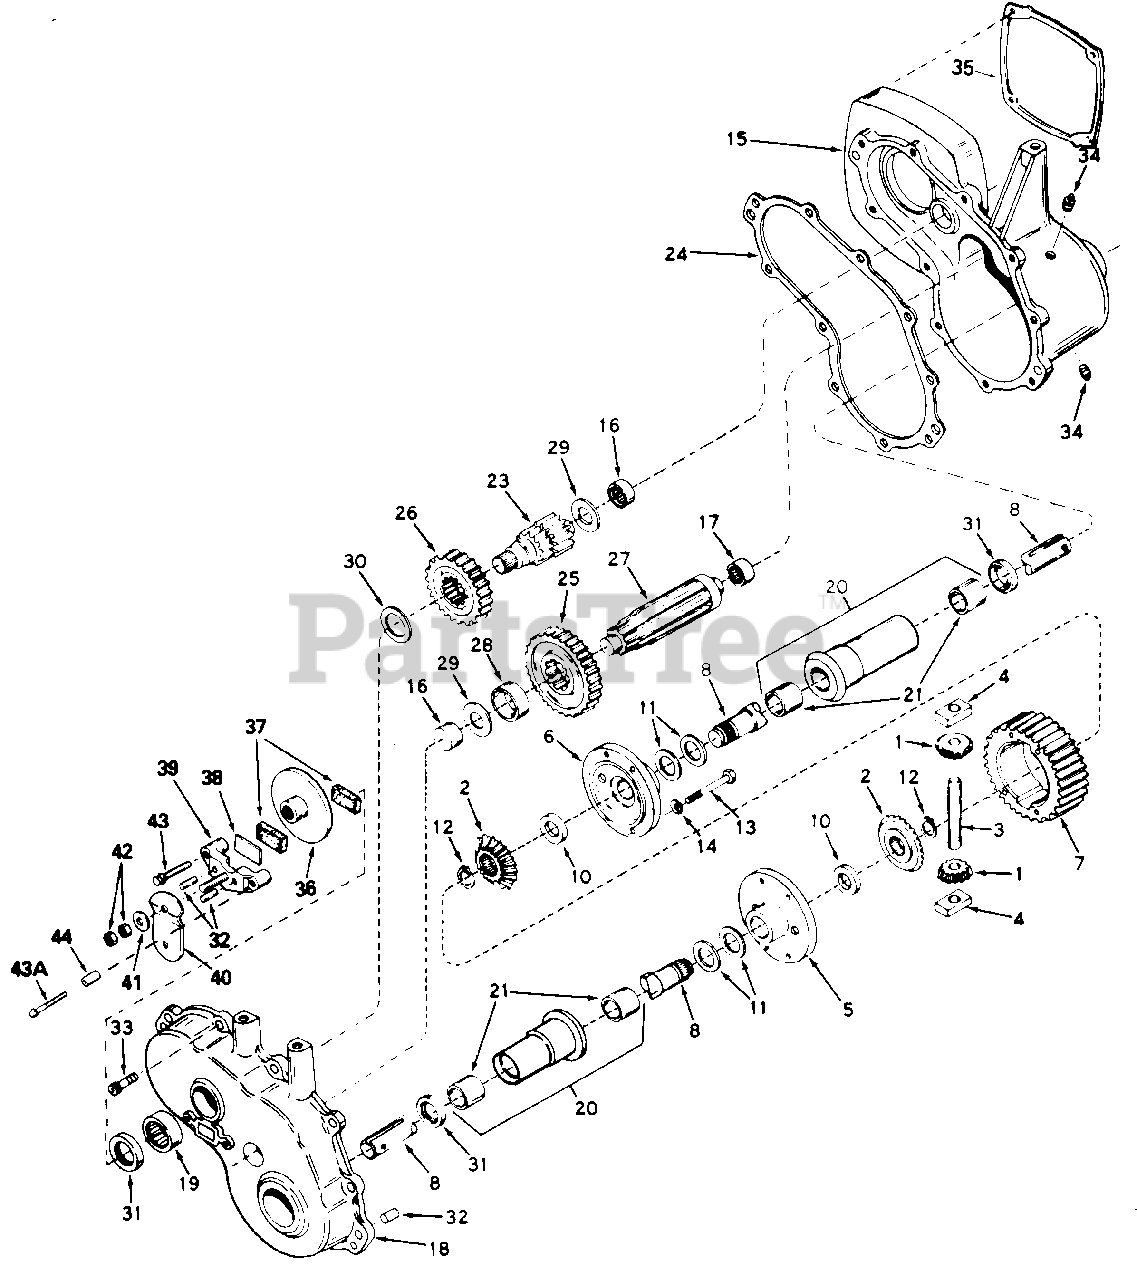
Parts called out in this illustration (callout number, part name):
1	Pinion, Bevel
2	Gear, Bevel
3	Pin, Drive
4	Block, Drive
5	Carrier, Differential
6	Carrier, Differential
7	Gear, Ring
8	Axle (16-1/64" Long)
10	Washer
11	Washer, Thrust
12	Ring, Snap
13	Screw, Hex Hd. 1/4-20 x 21/4
14	Lock Washer, 1/4"
15	Case Ass'y.
16	Bearing, Needle
17	Bearing, Needle
18	Cover Ass'y.
19	Bearing, Needle
20	Housing Ass'y., Axle
21	Bushing
23	Shaft, Brake
24	Gasket, Case to Cover
25	Gear, Output
26	Gear, Idler
27	Shaft, Output
28	Spacer
29	Washer
30	Washer
31	Seal, Oil
32	Pin, Dowel
33	Screw, Hex Hd., Self-Tapping, 1/4-20 x 1
34	Plug, Pipe
35	Gasket
36	Disc, Brake
37	Pad, Brake
38	Plate, Brake Pad
39	Holder, Brake Pad
40	Lever, Brake
41	Washer, Flat
42	Lock Nut 5/16-24
43	Screw, Hex Hd., Self-Tapping, 1/4-20 x 11/4
43A	Screw, Hex Hd., Self-Tapping, 1/4-20 x 2-1/4
44	Spacer
